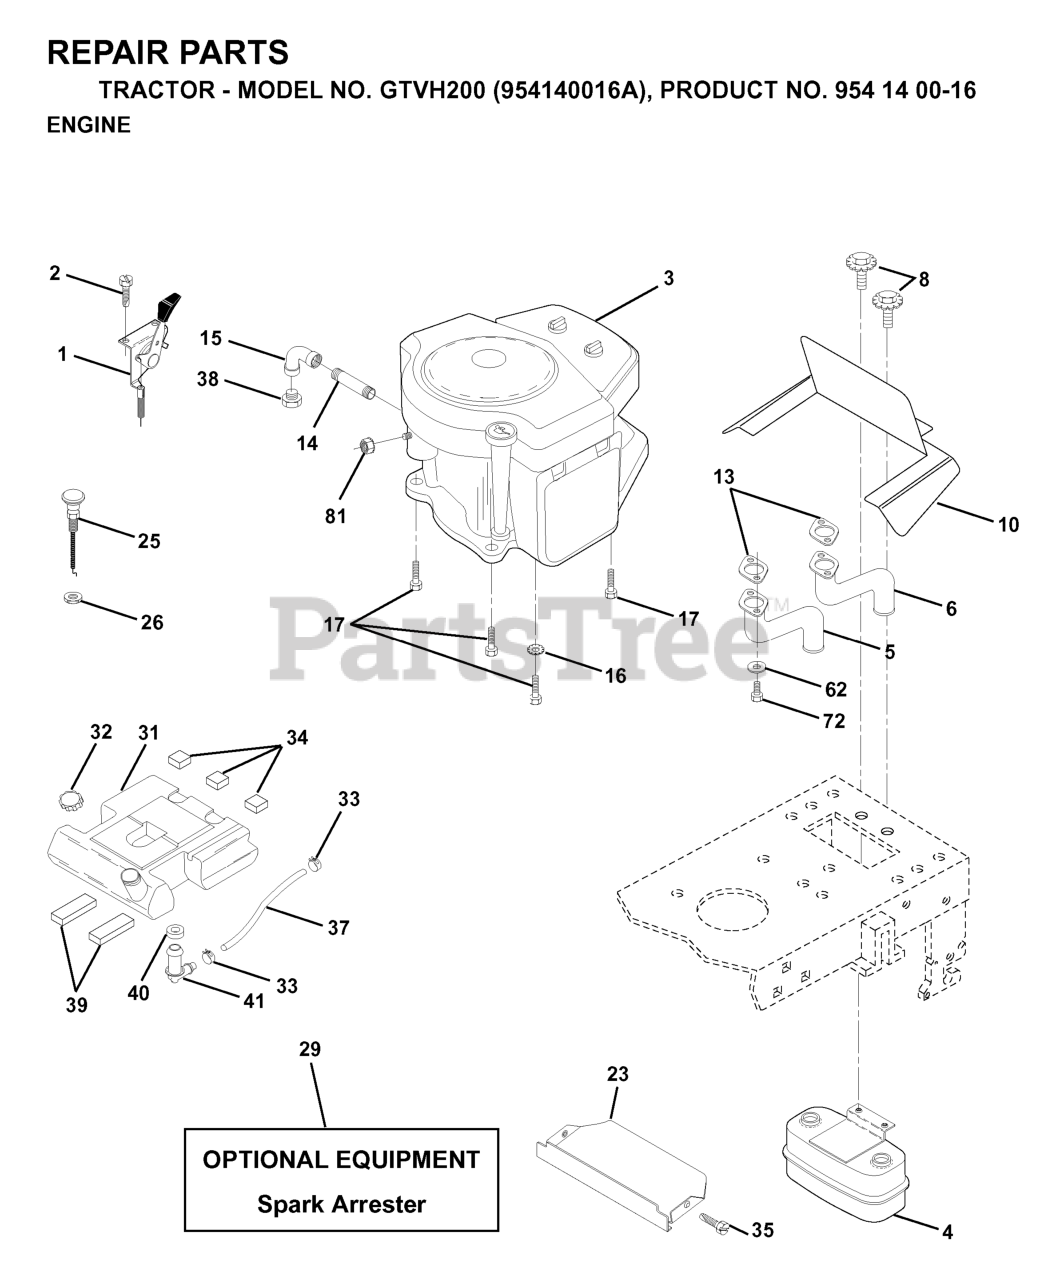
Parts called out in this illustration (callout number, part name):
1	WEIGHT, 36LBS
2	HOUSING W/DECALS ORANGE
3	DRIVE GUARD W/DECALS HUS
4	FASTENER KIT
5	PAINT 12.5 OZ SPRAY ORANGE
